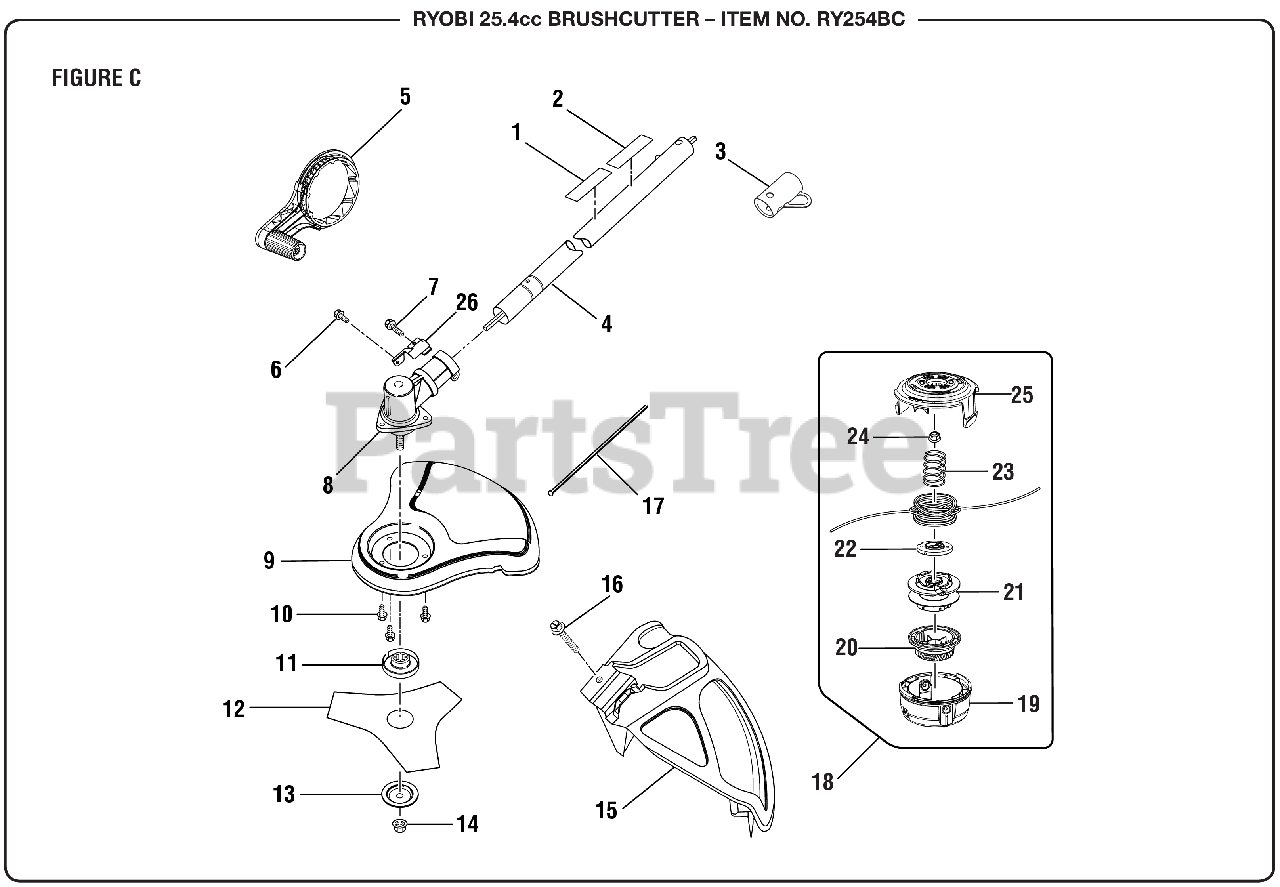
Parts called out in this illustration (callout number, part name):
1	Ryobi EXPAND-IT Label
2	Brushcutter Safety Label
3	Storage Hanger Cap
4	Lower Straight Shaft Boom Assembly
5	Crank Handle Assembly
6	Screw (1/4-20 x 1-1/4 in., Hex Washer Hd. S.T.)
7	Screw w/Washer (10-24 x 5/8 in., Hex Hd. T.F.)
8	Gear Case Assembly
9	8 in. Blade Guard
10	Screw w/Washer (10-24 x 1/2 in., Slotted Hex Hd.)
11	FLANGED WASHER
12	BLADE (TRI-ARC(TM))
13	CUPPED WASHER
14	Lock Nut (M8 x 1.25 in., Left Hand Threads)
15	Grass Deflector Assembly
16	SCREW (#1/4-20 X 1-1/4 in. HEX WASHER HD.)
17	Gear Head Locking Tool
18	Trimmer Head Assembly (.095)
19	Lower Housing
20	Bump Knob (Green)
21	Spool Assembly
22	String Guide
23	Compression Spring
24	Hex Nut (M8, Left Hand Threads)
25	Upper Housing
26	Grass Deflector Clamp
